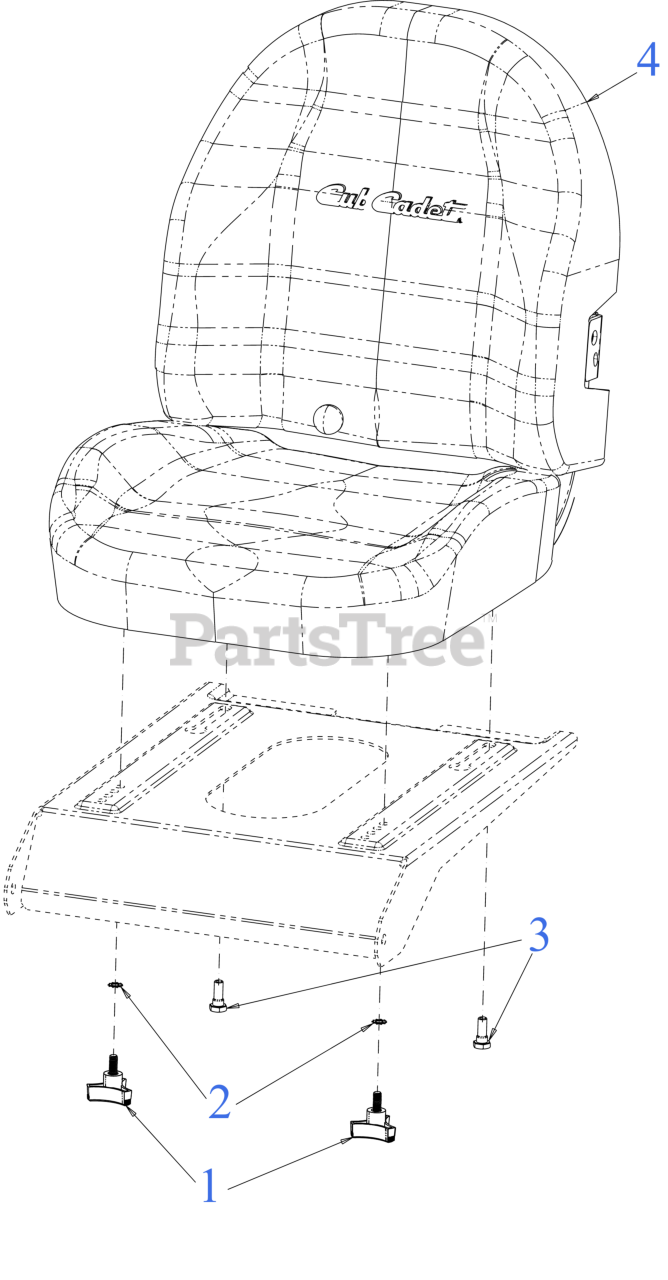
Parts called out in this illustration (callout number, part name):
1	3 PRONG KNOB 5/16-18
3	SHOULDER SCREW .437
4	SEAT (CUB/MINDA)
4	SEAT SWITCH (NC/NO)
